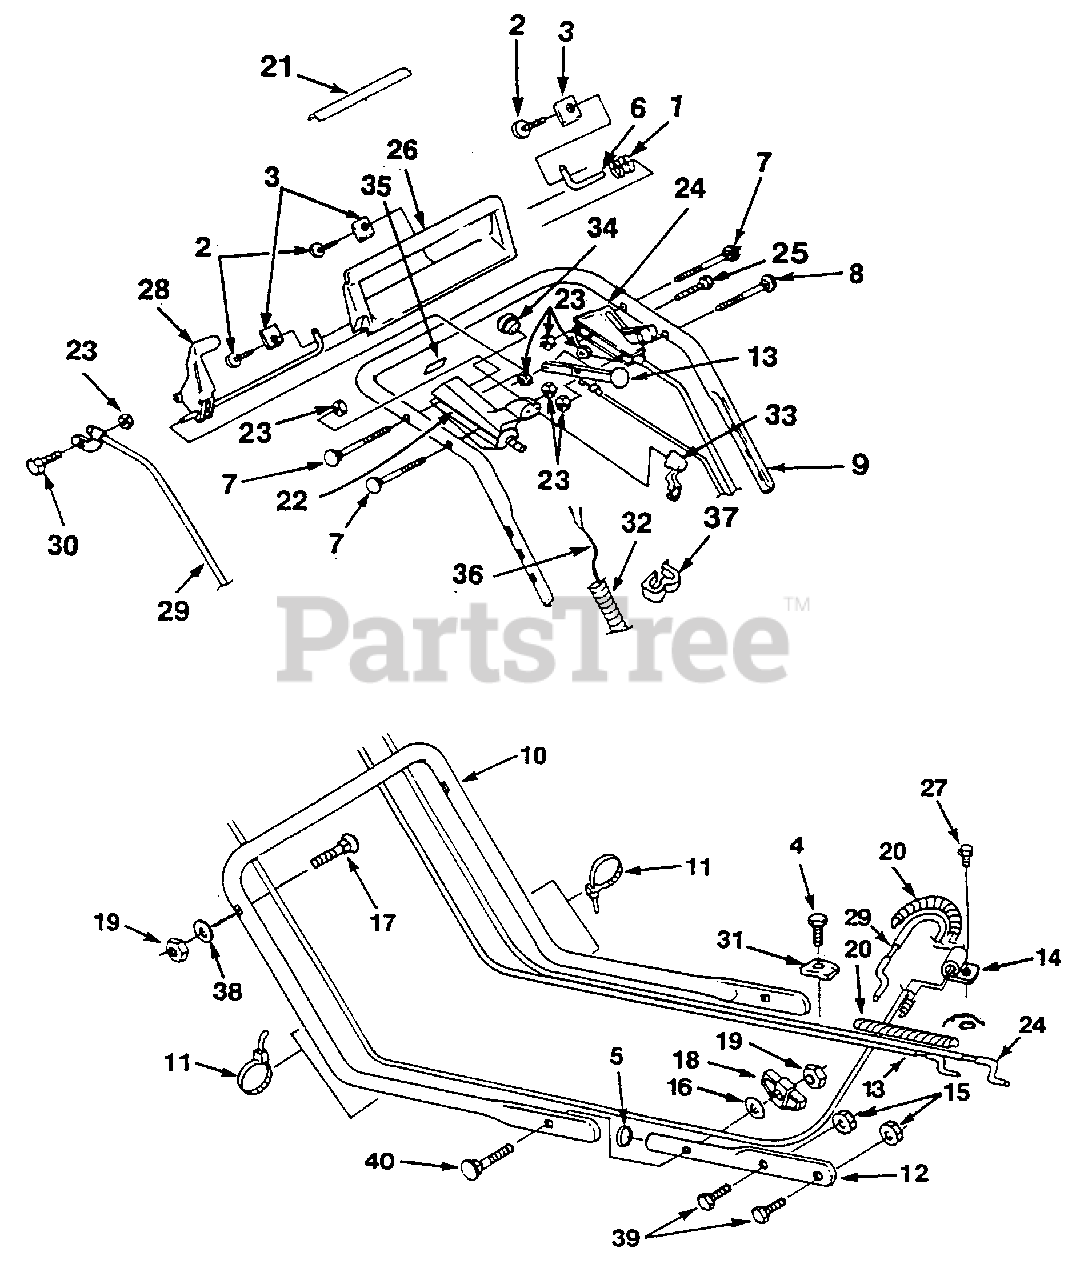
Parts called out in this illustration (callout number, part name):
1	SPRING - Compression
2	SCREW - 1/4 - 10 x 5/8
3	CLAMP - Pivot shaft
4	SCREW - 1/4-20 x 1/2 Hex Tap
6	SHAFT - Pivot
7	BOLT - Sq. nk.
8	BOLT - Sq. nk.
9	HANDLE - Upper
10	HANDLE - Lower
11	CABLE - Tie
12	STUB - Handle mtg.
13	SHIFT - Gear
15	NUT - Flange 5/16-18
16	WASHER - Flat 5/16
17	BOLT - 5/16-18 x 1 1/2'
18	KNOB - Handle
19	NUT - Hex 5/16-18
20	COVER - Cable
21	DECAL - Starting Instr.
22	ENGINE CONTROL
23	NUT - Lock 1/4-20
24	CONTROL - Throttle
25	SCREW - Hex 1/4 - 20 x 2"
26	BAIL - Brake control
27	SCREW - Hex 1/4-20 x 5/8"
28	TRACTION LEVER ASSY.
29	CABLE - Traction control
30	SCREW - 1/4-20 x 1 1/2"
32	COVER - Control cable
33	HOUSING - Switch
36	HARNESS - Wiring
37	CUP - Cover
38	WASHER - Lock 5/16-18
39	BOLT - Hex 5/16 - 18 x 1"
40	BOLT - Handle Joining
